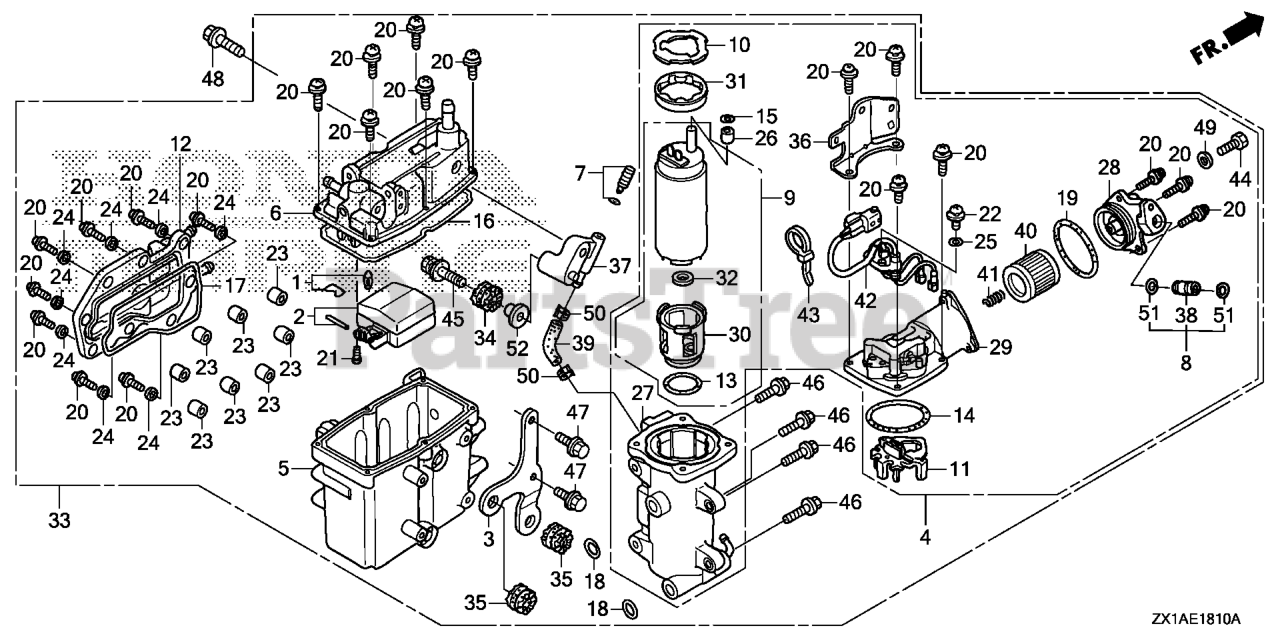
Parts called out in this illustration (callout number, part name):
1	VALVE SET, FLOAT
3	STAY A, PLATE
4	PUMP UNIT, FUEL (MSDS)
5	BODY, CHAMBER
7	SCREW SET, DRAIN (CARBURETOR NO.)
9	PUMP UNIT, FUEL (B) (MSDS)
12	COVER, WATER JACKET
15	O-RING (7.3X2.2) (NOK)
20	SCREW-WASHER
21	SCREW, PAN
22	SCREW, WASHER
23	COLLAR, SET
24	WASHER, PLAIN
25	WASHER, PLAIN
27	CASE, PUMP
28	COVER B, PUMP
29	COVER, PUMP (A)
33	SEPARATOR ASSY., VAPOR
34	GROMMET, VAPOR SEPARATOR
35	GROMMET, VAPOR SEPARATOR
36	STAY, PLATE
37	STAY, VAPOR SEPARATOR
38	JOINT, FUEL PIPE
39	TUBE F, FUEL
40	SCREEN, FUEL STRAINER
41	SPRING, SET
44	BOLT, SEALING (6MM)
45	BOLT-WASHER (8X35)
46	BOLT, FLANGE (6X25)
47	BOLT, FLANGE (6X16)
48	BOLT, FLANGE (8X30)
49	WASHER, SEALING (6MM)
50	CLAMP, TUBE (8.0)
51	O-RING (7.8X1.9) (ARAI)
52	COLLAR (8.5X14.5)
